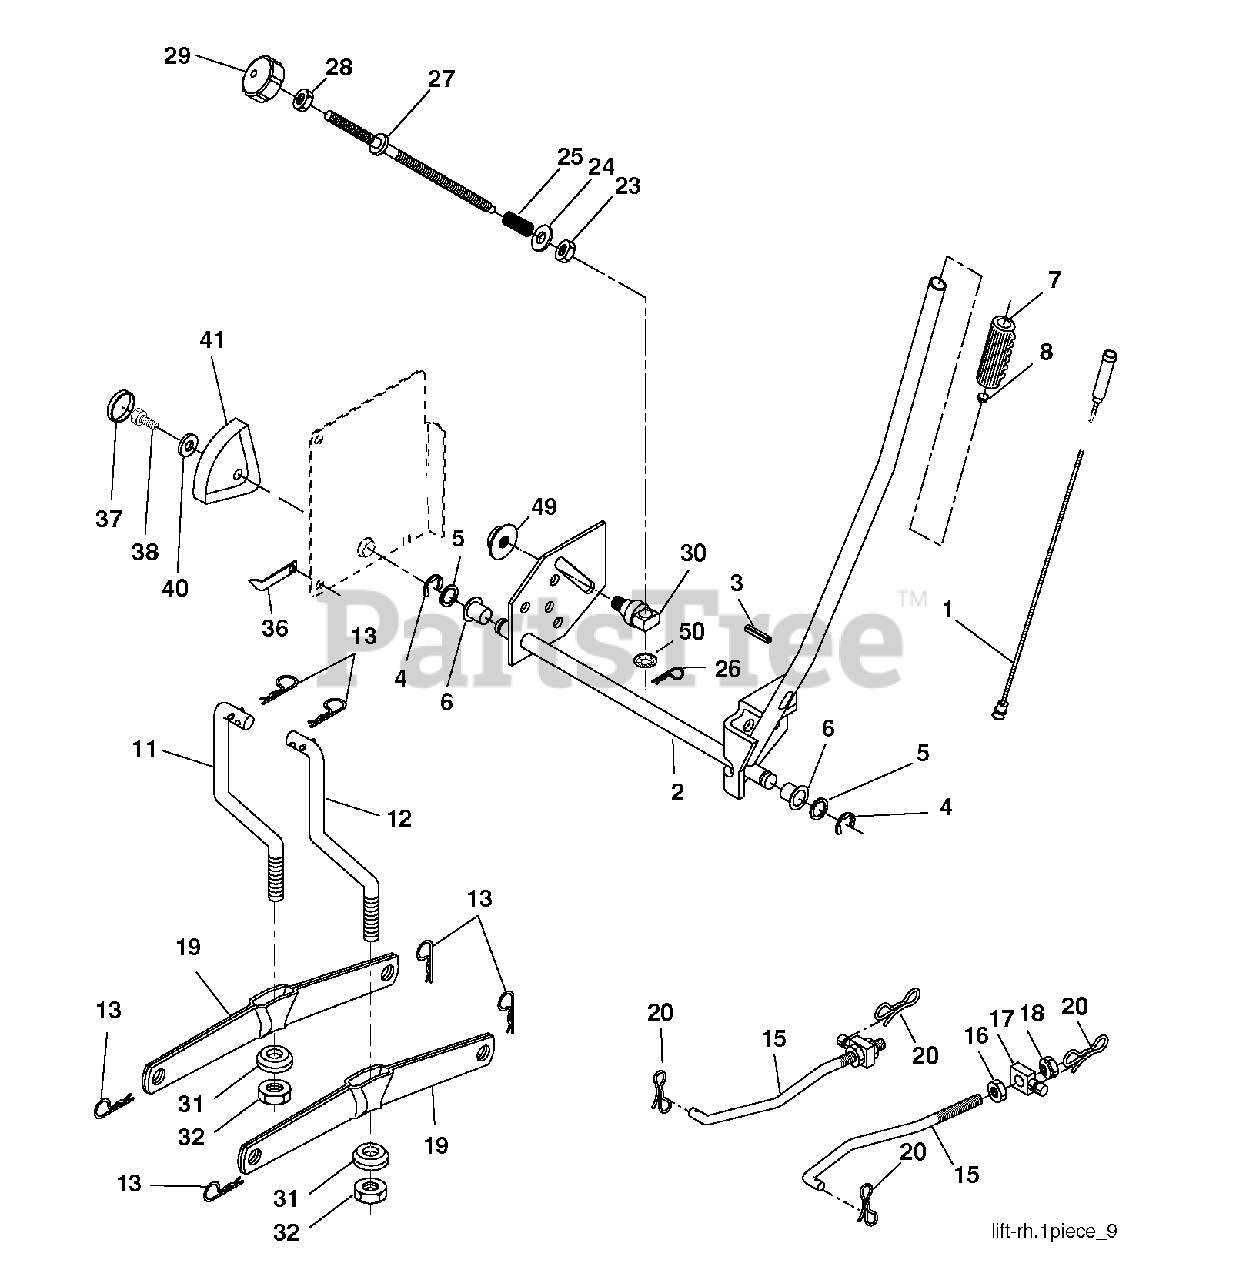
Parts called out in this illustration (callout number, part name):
1	PLUNGER.ASM.LIFT.LVR.BLK.17.32
2	SHAFT ASM R HANDLE
3	PIN GROOVE
4	RETAINING RING LT
6	BEARING.NYLON
7	GRIP HANDLE
8	PLUNGER BUT KIT
11	LINK LIFT LH
12	LINK LIFT RH
13	RETAINER-SPRNG RB
16	NUT
18	NUT
19	ARM.REAR.SUSPENSION
20	PIN.COTTER.7/16.BOW TI
25	SPRING**
26	RETAINER CLIP
27	ROD ADJ LIFT
28	NUT
29	KNOB INF 3/8-16
31	BEARING.PIVOT.LIFT
32	NUT CROWNLOCK 3/8-24
36	POINTER, HEIGHT INDICATOR
37	PLUG,HOLE
38	SCREW 5/16-18X1
41	HEIGHT INDICATOR
49	NUT
50	NUT PUSH M
